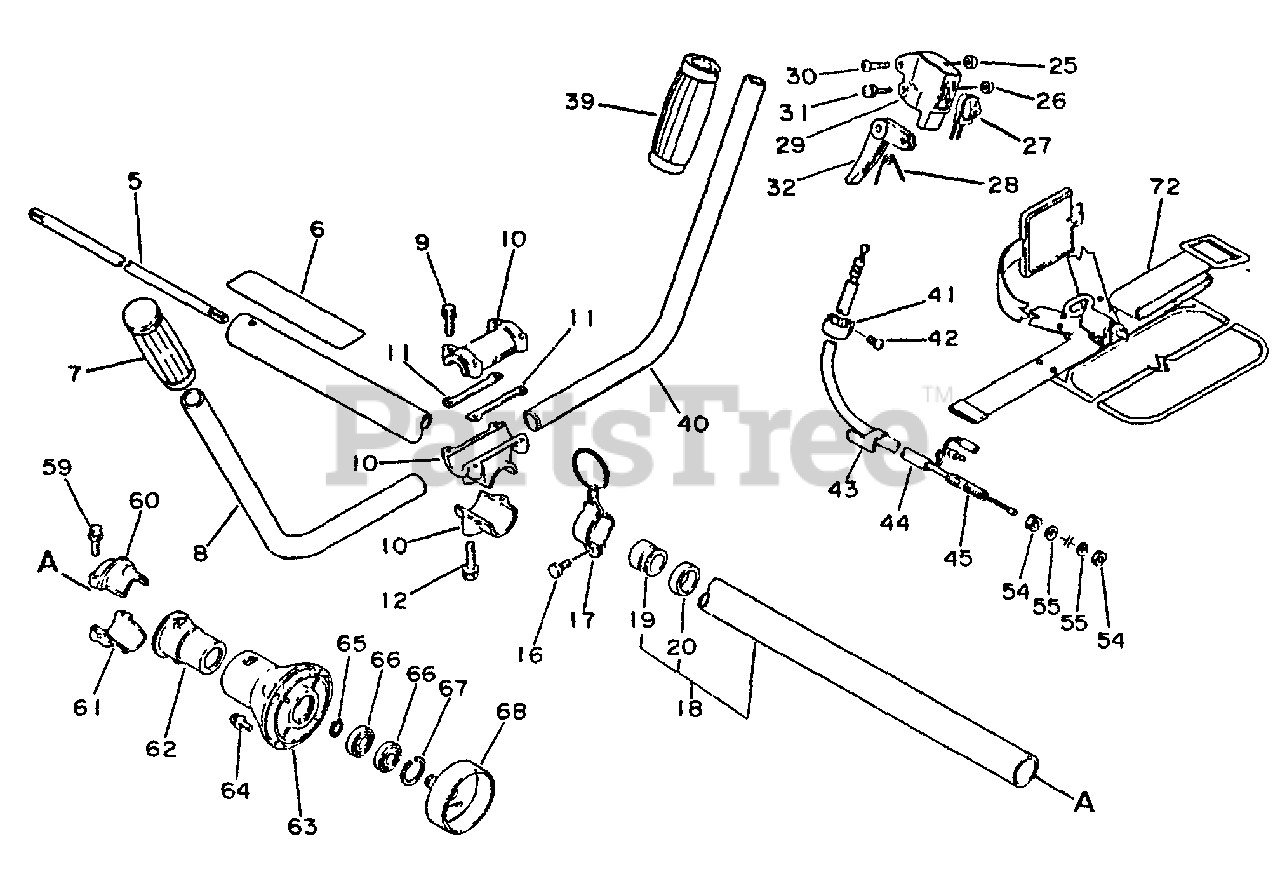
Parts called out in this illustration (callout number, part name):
5	DRIVESHAFT
6	LABEL
7	GRIP, HANDLE
8	HANDLE, LEFT
9	BOLT 5×25
10	BRACKET ASSY, HANDLE
12	BOLT 6×30
16	HANGER KIT
17	BOLT 5×12
18	MAIN PIPE ASSY
25	LOCKNUT - 5
26	NUT M5
27	SWITCH, ON-OFF
29	BRACKET, THROTTLE
31	SCREW 5×30
32	TRIGGER, THROTTLE
42	SCREW 5×10
45	CABLE, THROTTLE
55	WASHER 6.5×11.5×0.8
59	BOLT - 5×25
60	HOLDER
61	HOLDER
63	CASE, CLUTCH
65	RING, RETAINING - 12
66	BEARING, BALL 6001
67	RING, SNAP 28
68	DRUM, CLUTCH
72	SHOULDER STRAP ASSY
